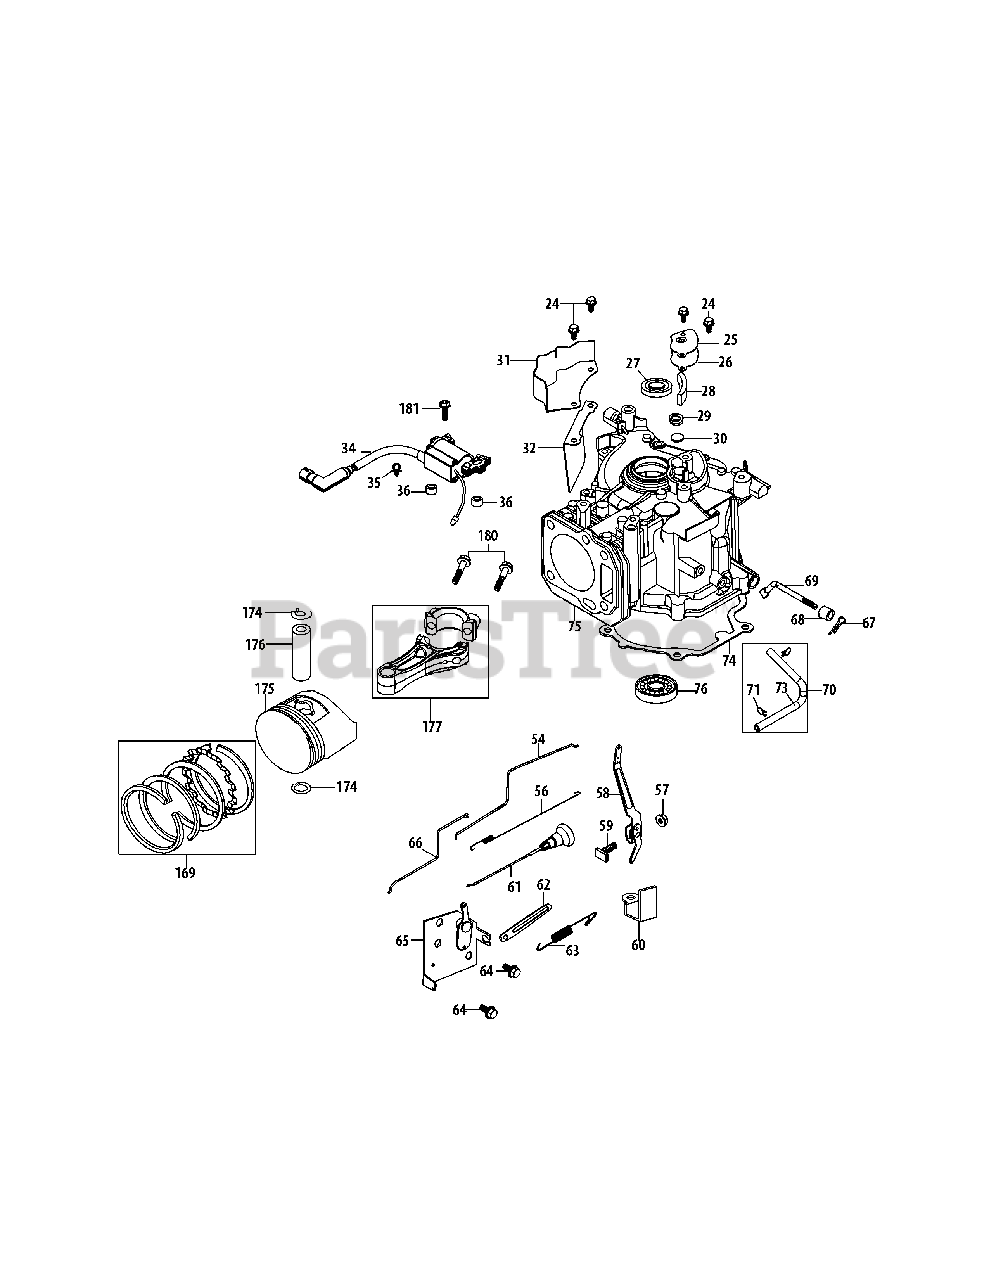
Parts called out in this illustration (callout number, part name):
24	Bolt M6×14
25	Breather Cover Plate
26	Breather Gasket
27	Upper Crankshaft Seal
28	Breather Screen
29	Breather Spring
30	Breather Valve
31	Engine Brake Cover Plate
32	Label Bracket
34	Ignition Coil Assembly
35	Plastic Clamp 5.8×9
36	Ignition Coil Spacer
54	Throttle Linkage
55	Throttle Linkage Spring
57	Governor Arm Nut M6
58	Governor Arm
59	Governor Arm Bolt
60	Governor Arm Guard
61	Choke Control
62	Flexible Clamp
63	Governor Spring
64	Bolt M6×12
65	Component Bracket
66	Choke Linkage
67	Governor Arm Cotter Pin
68	Governor Seal
69	Governor Arm Shaft
70	Breather Hose Assembly
71	Breather Hose Clamp
73	Breather Hose
74	Crankcase Cover Gasket
75	Short Block Assembly
76	Main Bearing
169	Piston Ring Set
174	Piston Pin Snap Ring
175	Piston
176	Piston Pin
177	Connecting Rod Assembly
180	Connecting Rod Bolt
181	Bolt M6×30
